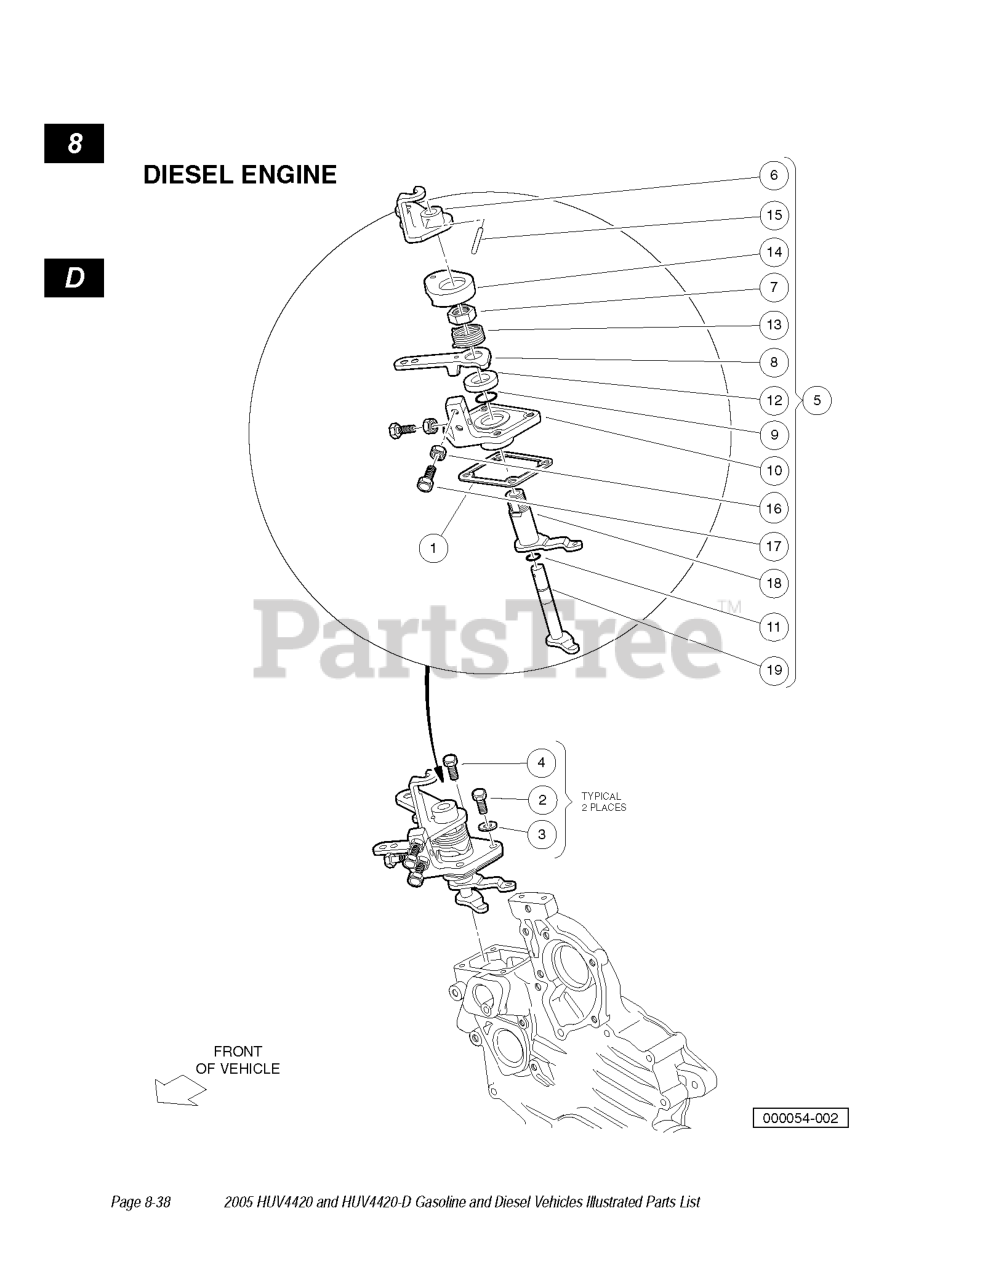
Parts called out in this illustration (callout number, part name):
1	GASKET, CONTROL PLATE
2	BOLT, M6X1X30
3	GASKET, 6X10
4	BOLT, D722 INTAKE MANFLD LOWER
5	ASSY-SPEED PLATE
6	LEVER, ENGINE STOP
7	NUT, SPEED CONTROL
8	LEVER, SPEED CONTROL
9	O RING, 19X16
10	PLATE, SPEED CONTROL
11	O RING, 9X7
12	COLLAR, LEVER
13	SPRING, RETURN
14	CAP, SPEED CNTRL PLATE RTRN
15	PIN, SPRING, SPEED PLATE
18	LEVER-GOVERNOR
